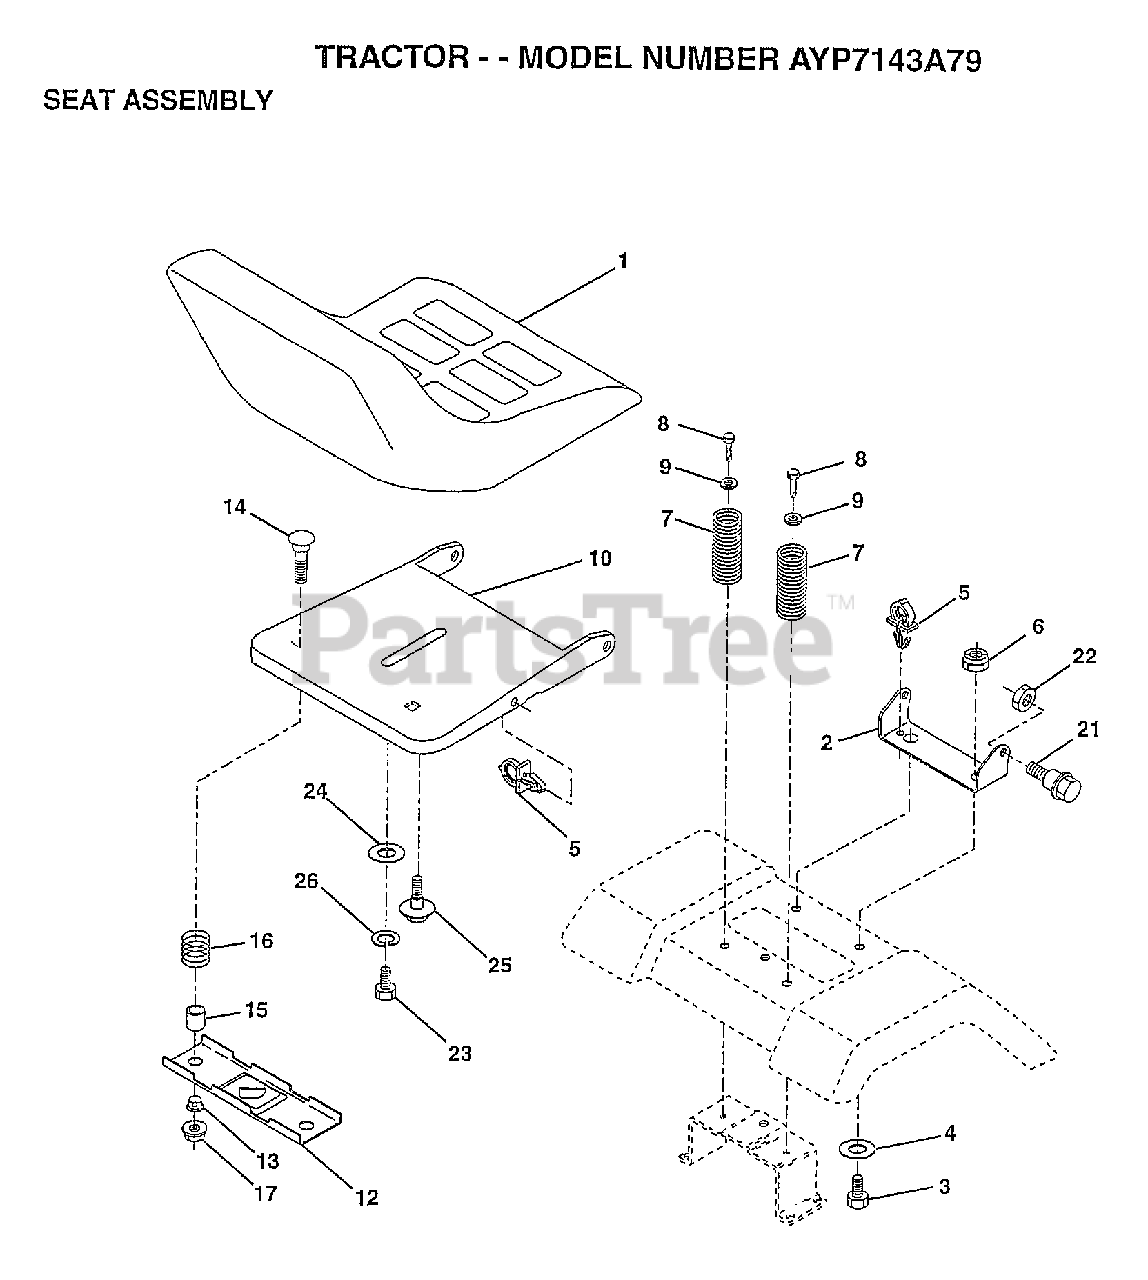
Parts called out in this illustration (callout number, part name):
2	BRACKET PVT SEAT
3	BOLT
4	WASHER PM
5	CLIP.PUSH-IN.HING
6	NUT
7	SPRING COMPRESSIO
8	SCREW GTV
9	WASHER
10	PAN-SEAT
12	BRKT SWITCH
13	BUSHING
15	SPLIT SPACER
16	SPRING
21	"BOLT,SHOULDER"
22	NUT
23	BOLT
24	WASHER
25	"BOLT,SHOULDER"
26	LOCKWASHER
